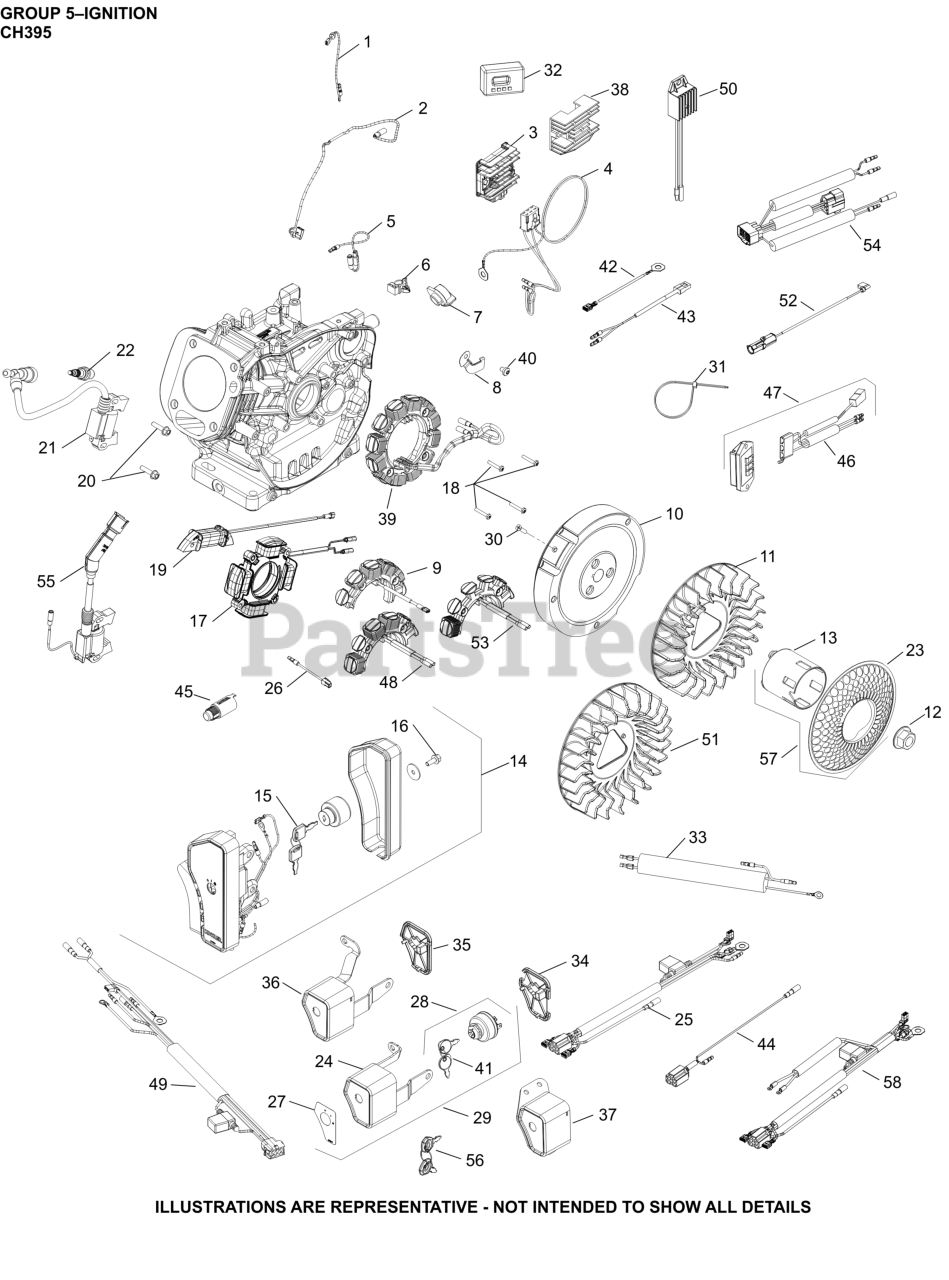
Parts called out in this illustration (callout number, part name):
2	LEAD, GROUND TO KILL
4	HARNESS, REGULATOR WIRING ASSY
8	BRACKET, STATOR WIRE
9	STATOR ASSEMBLY, 10A
10	FLYWHEEL ASSY ELECTRIC START (CH395)
11	FAN, FLYWHEEL
12	NUT, FLYWHEEL
13	CUP, STARTER DRIVE
14	HOUSING, KEY BOX ASSY-USE 17 755 69-S
15	KEYS FOR SWITCH
16	SCREW, HEX FLANGE (M6)-USE 25 086 433-S
18	SCREW, STATOR MOUNTING
20	SCREW, M6 X 25-(#25086436S)
21	MODULE, SPARK PLUG ASSY
22	SPARK PLUG
24	KIT, KEYBOX HOUSING ASSEMBLY
25	HARNESS, WIRING ASSEMBLY (10 AMP)
27	LABEL, KEY BOX
28	SWITCH, KEY ASSEMBLY
29	KIT, KEY BOX ASSEMBLY
29	KIT,KEY BOX CONVERSION CH395 (10&18 AMP)
34	COVER, KEY BOX
38	REGULATOR, 10 AMP
40	SCREW, COIL BRACKET
41	KEY, SET OF 2
56	KIT, KEY PLASTIC HANDLE (2 PC)
